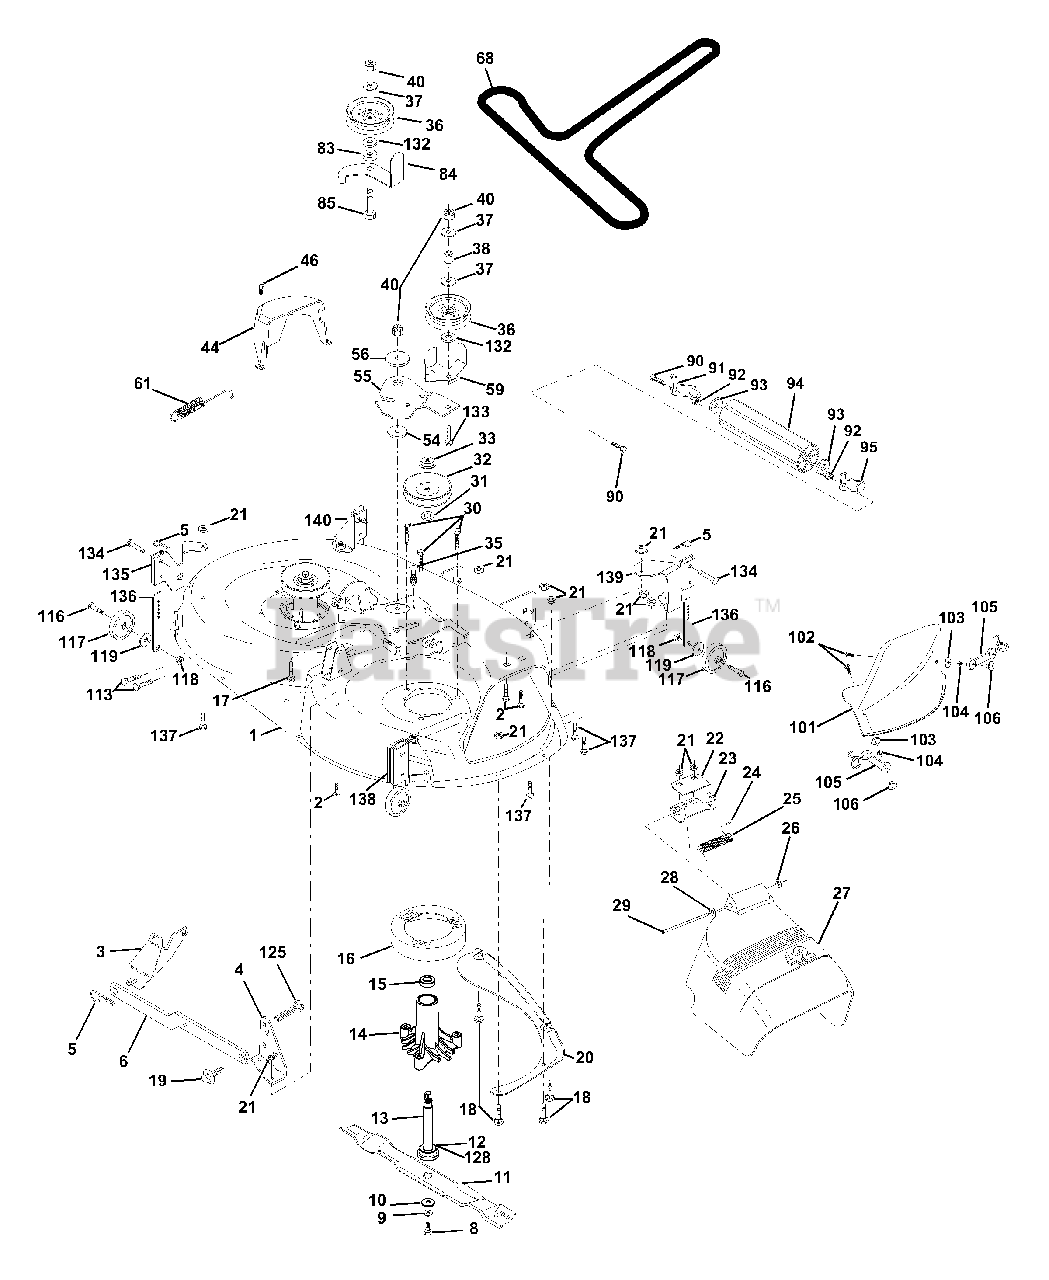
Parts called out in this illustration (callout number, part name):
1	Deck Weldment Mower 42" W/Adj
2	Bolt Rdhd Sqnk 5/16-18unc X3/4
3	Bracket Asm Fr Sway Bar 38/42
4	Bracket Asm Deck 42"sway Bar
5	Retainer Spring
6	Arm Suspension Rear
8	Bolt 3/8-24x1 25 Gr8 Patched
9	Washer Lock Hvy 3/8 Unplated
10	Washer Hard Blade Mower Vented
11	Blade Mower Mulching 42"
12	Bearing Ball #6204 (Mandrel)
13	Shaft Asm W/lower Bearing
14	Housing Mandrel Vented(machd)
15	Bearing Ball Mandrel
16	Stripper Round Mower
17	Bolt Rdhd Sqnk 3/8-16 X 2-1/4
18	Bolt Carr 5/16-18 X 5/8
19	Bolt Shoulder
20	Baffle Vortex 42
21	Nut Crown Lock 5/16-18
22	Stiffener Bracket 42"deck
23	Bracket Deflector Mower 42"
24	Cap Sleeve 80x 112 Blk Mower
25	Spring Torsion Deflector 2 52
26	Nut Push Phos & Oil
27	Shield Deflector Mower 42" Blk
28	Washer 11/32 X 5/8 X 16 Ga
29	Rod Hinge 42"6 75 Wlg
30	Screw Thdrol Washer Head
31	Washer Spacer Mower Vented
32	Pulley Mandrel 42"
33	Nut 9/16top Lock Flng Cntr
35	Fastner Christmas Tree
36	Pulley Idler Flat 3 060
37	Washer 13/32 X 13/16 X 16 Ga
38	Spacer Spring Stop Idler
40	Nut Lock 3/8-16 Unc
44	Guard Mandrel LH Black
46	Screw Thdrol 1/4-20x5/8
54	Washer Hardened
55	Arm Idler 42"mower LT/YT
56	Spacer Retainer Pm Mower
58	Spring Ext Elect CL 38 & 42" Deck
59	Guard, Belt
61	Spring Ext. Elect
68	V-Belt Mower
83	Washer Sintered
84	Keeper 'Belt Idler
85	Bolt Carriage 3/8-16 x 2-1/4 Gr.5
90	Bolt Fin Hex 3/8-16unc X 1
91	Bracket Asm Noseroller LH
92	Nut Lock Hex w/ins. 3/8-16 UNC
93	Washer 17/32 X 7/8 X 16 Ga
94	Roller Nose 38 & 42
95	Bracket Asm Noseroller RH
101	Cover Mulching 42" Blk
102	Screw
103	Washer #10
104	Washer Lock #10
105	Latch Asm Bagger
106	Nut Weld .327/.304 #10-24
116	Bolt Shld
117	Wheel Gauge blk. 4.93
118	Nut Centerlock 3/8 - 16 UNC
119	Washer 3/8 x 7/8 x 14 Ga.
125	Cotter Pin
128	Washer Felt
130	Bolt Fin Hex 3/8-16 UNC x 1 Gr. 5
132	Washer 13/32 x 1-3/8 x 3 Ga
133	Bolt Rdhd 3/8-16 UNC x 2-3/4 Gr.5
134	Pin Head Rivet
135	Bracket Asm Whl Ga Rear LH 42"
136	Bar Pnt Adjusting Wheel Gauge
137	Bolt Carr 5/16-18 x 5/8 Short
138	Bracket Asm Whl Ga. Rear RH 42"
139	Bracket Asm Whl Ga. Front RH 42"
140	Bracket Asm Whl Ga. Front RH 42"
